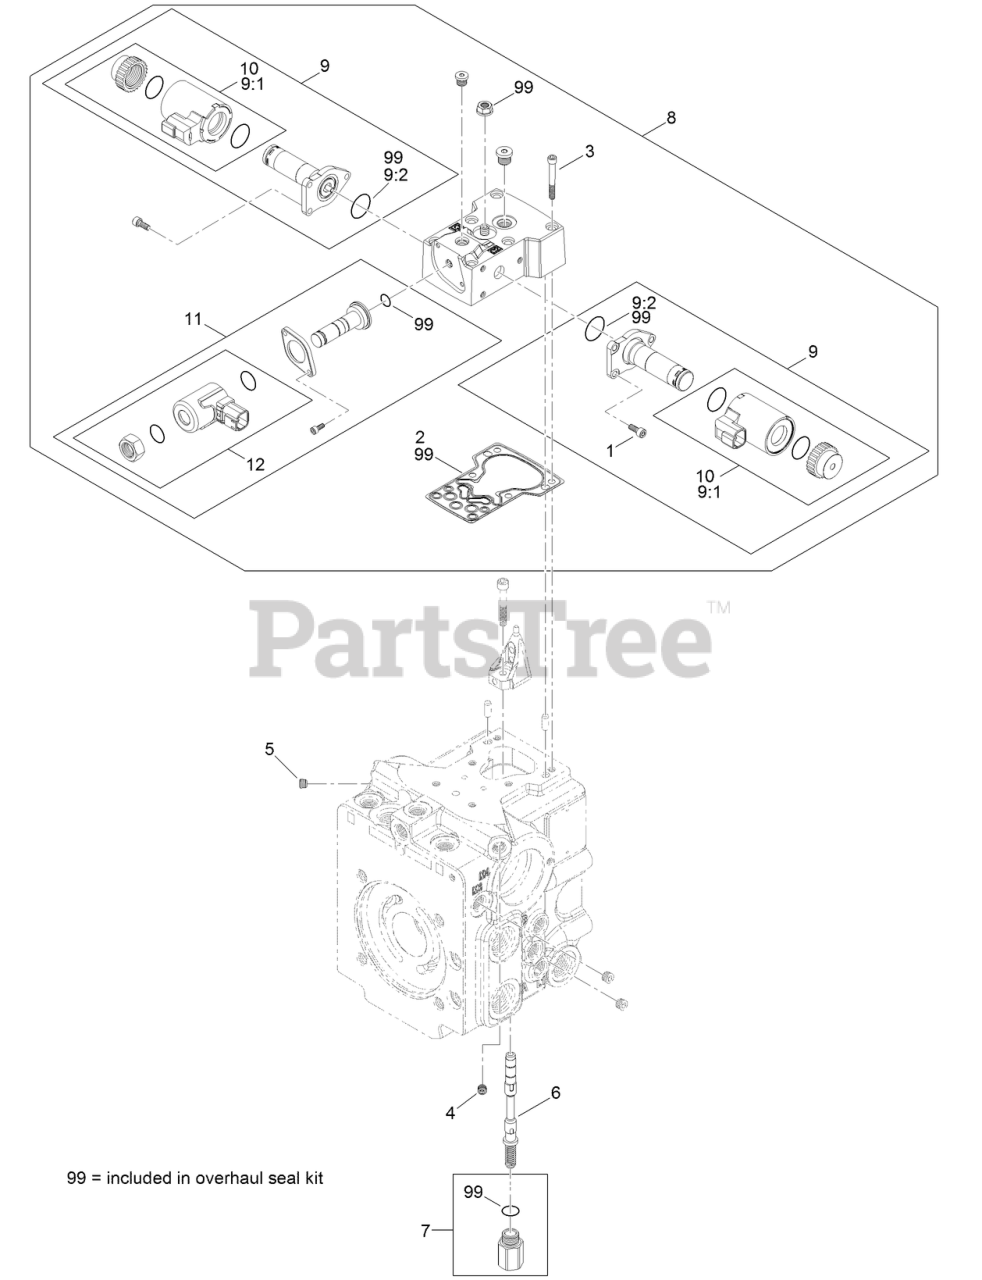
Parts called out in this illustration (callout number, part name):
2	GASKET-CONTROL
4	ORIFICE
5	ORIFICE
6	SPOOL ASM
7	PLUG ASM
8	E D C KIT
9	SOLENOID VALVE ASM
9:1	COIL KIT
9:2	O-RING
10	COIL KIT
11	VALVE-SOLENOID
12	COIL KIT
99	SEAL KIT
